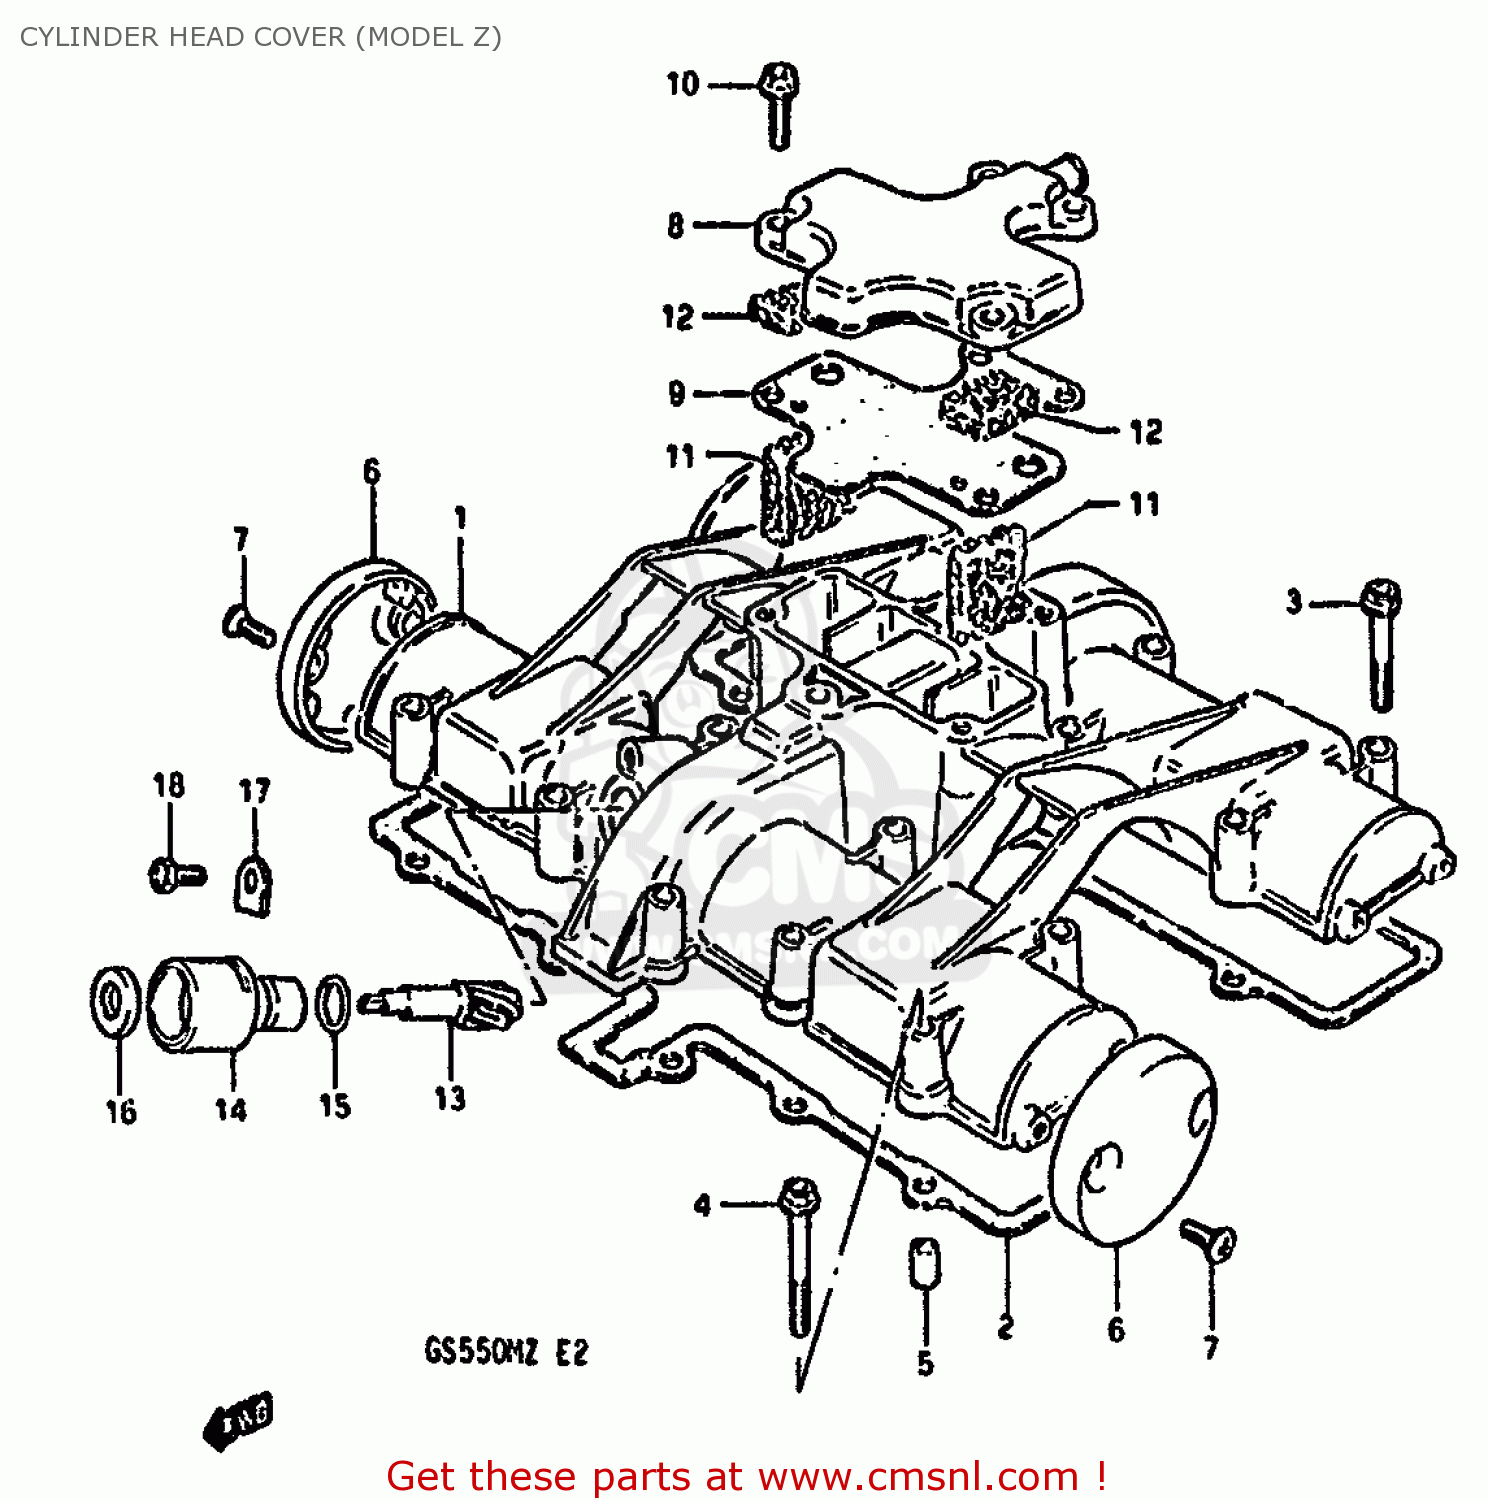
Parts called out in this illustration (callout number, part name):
1	COVER,CYLINDER HEAD
2	GASKET,CYLINDER HEAD COVER (MCA)
3	BOLT
4	BOLT,UNDER
5	PIN(6.2X8X11)
6	CAP,CYLINDER HEAD COVER
7	SCREW(5X12)
8	COVER,BREATHER
9	GASKET (MCA)
10	BOLT,REAR
11	COVER,BREATHER
12	SEPARATOR,OIL BREATHER
13	GEAR,TACHOMETER DRIVEN
14	SLEEVE,TACHOMETER DRIVE
15	SEAL,TACHOMETER DRIVEN
16	SEAL,OIL(5X12X8)
17	PLATE,TACH DRIVE GEAR SLEEVE
18	SCREW(5X12)
